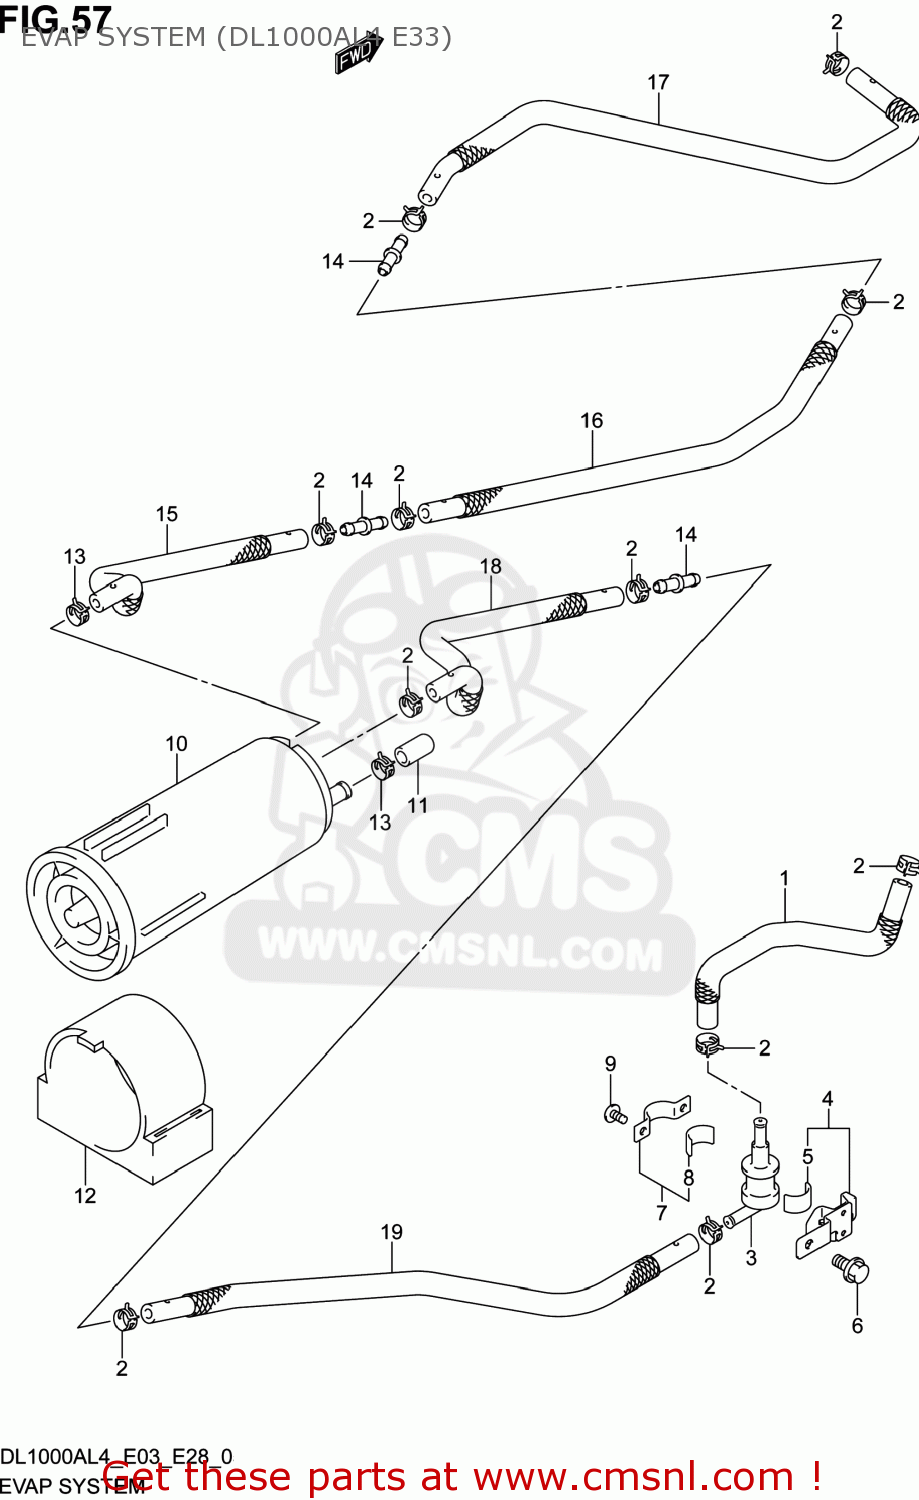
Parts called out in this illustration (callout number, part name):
1	HOSE,TANK & BREATHER VALVE
2	CLIP
3	VALVE,FUEL TANK BREATHER
4	PLATE,BREATHER VALVE
5	CUSHION
6	BOLT
7	PLATE,FUEL TANK BREATHER NO.2
8	CUSHION
9	SCREW
10	CANISTER ASSY,CHARCOAL
11	CAP,OD:11.5
12	CUSHION,CANISTER
13	CLIP
14	JOINT
15	HOSE,CSTR PURGE NO.1
16	HOSE,CSTR PURGE NO.2
17	HOSE,CSTR PURGE NO.3
18	HOSE,CSTR SURGE NO.1
19	HOSE,CSTR SURGE NO.2
